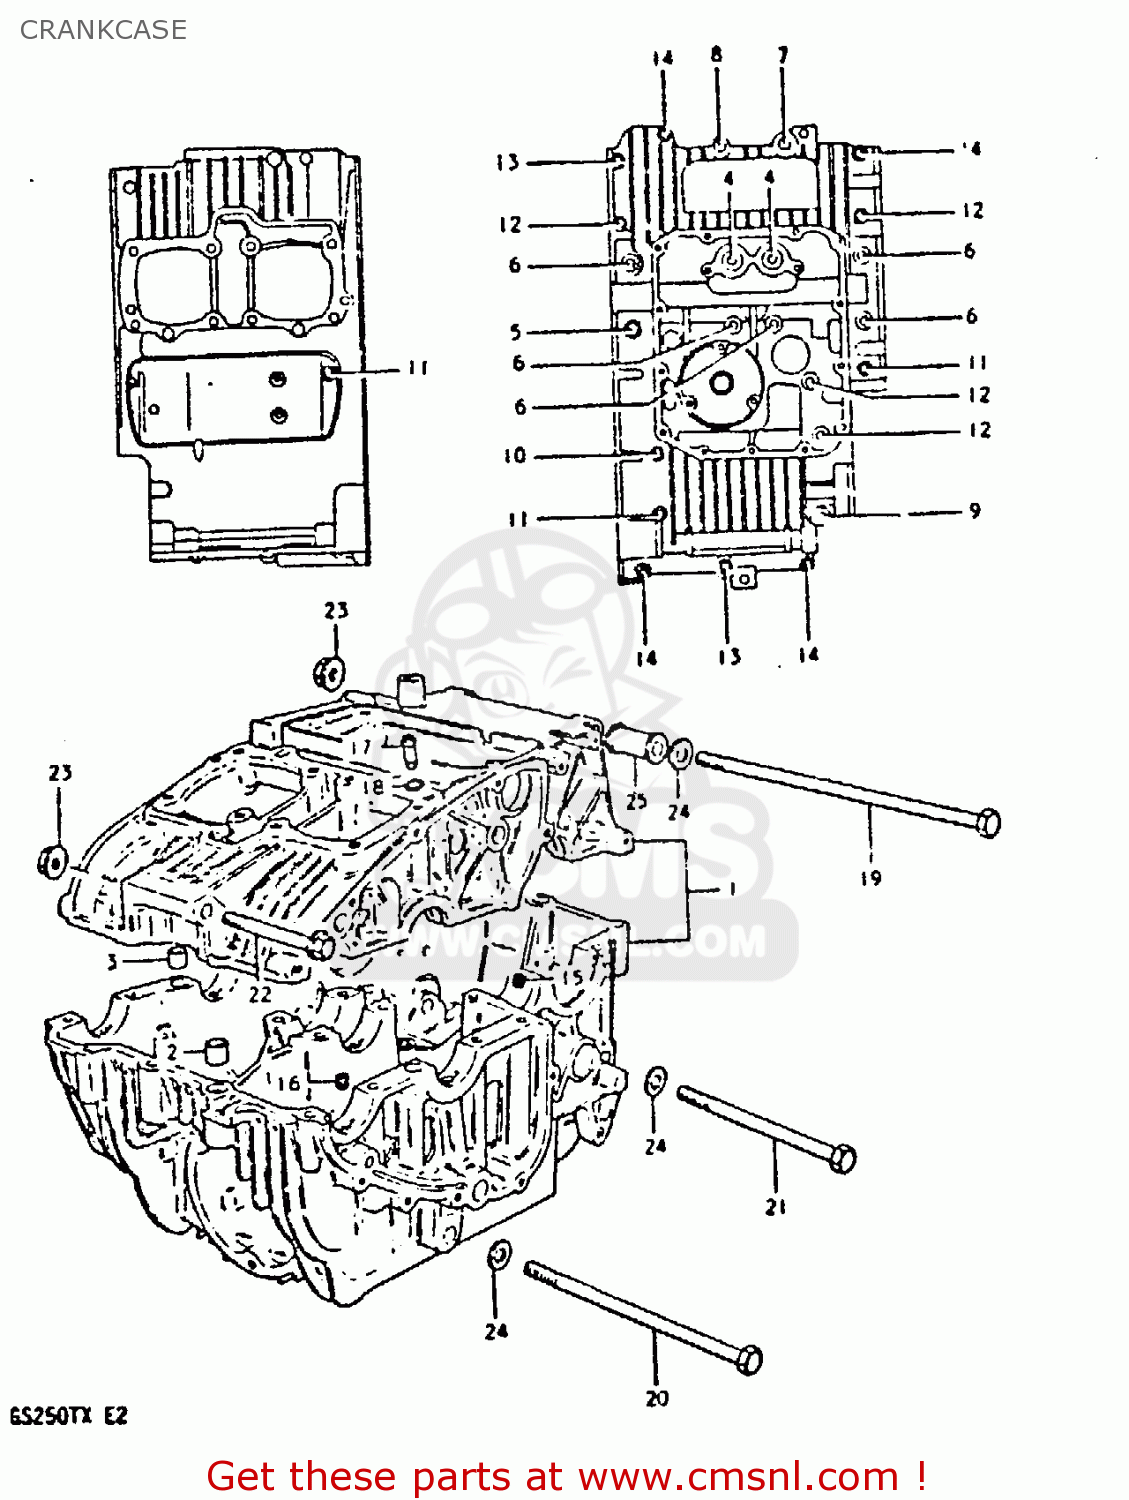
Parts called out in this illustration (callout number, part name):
1	CRANKCASE SET
2	PIN(10.4X13X22)
3	PIN (11X20)(SUS)
4	BOLT
5	BOLT
6	BOLT
7	BOLT 8X65
8	BOLT
9	BOLT (8X40)
10	BOLT
11	BOLT
12	BOLT (6X90)
13	BOLT (6X60)
14	BOLT,UNDER
15	JET,AIR(100)
16	JET,AIR
17	JET,AIR
18	O RING(D:1.05,ID:3.1)
19	BOLT 10X250
20	BOLT
21	BOLT 10X160
22	BOLT
23	NUT
24	WASHER
25	SPACER,ENGINE MOUNT
